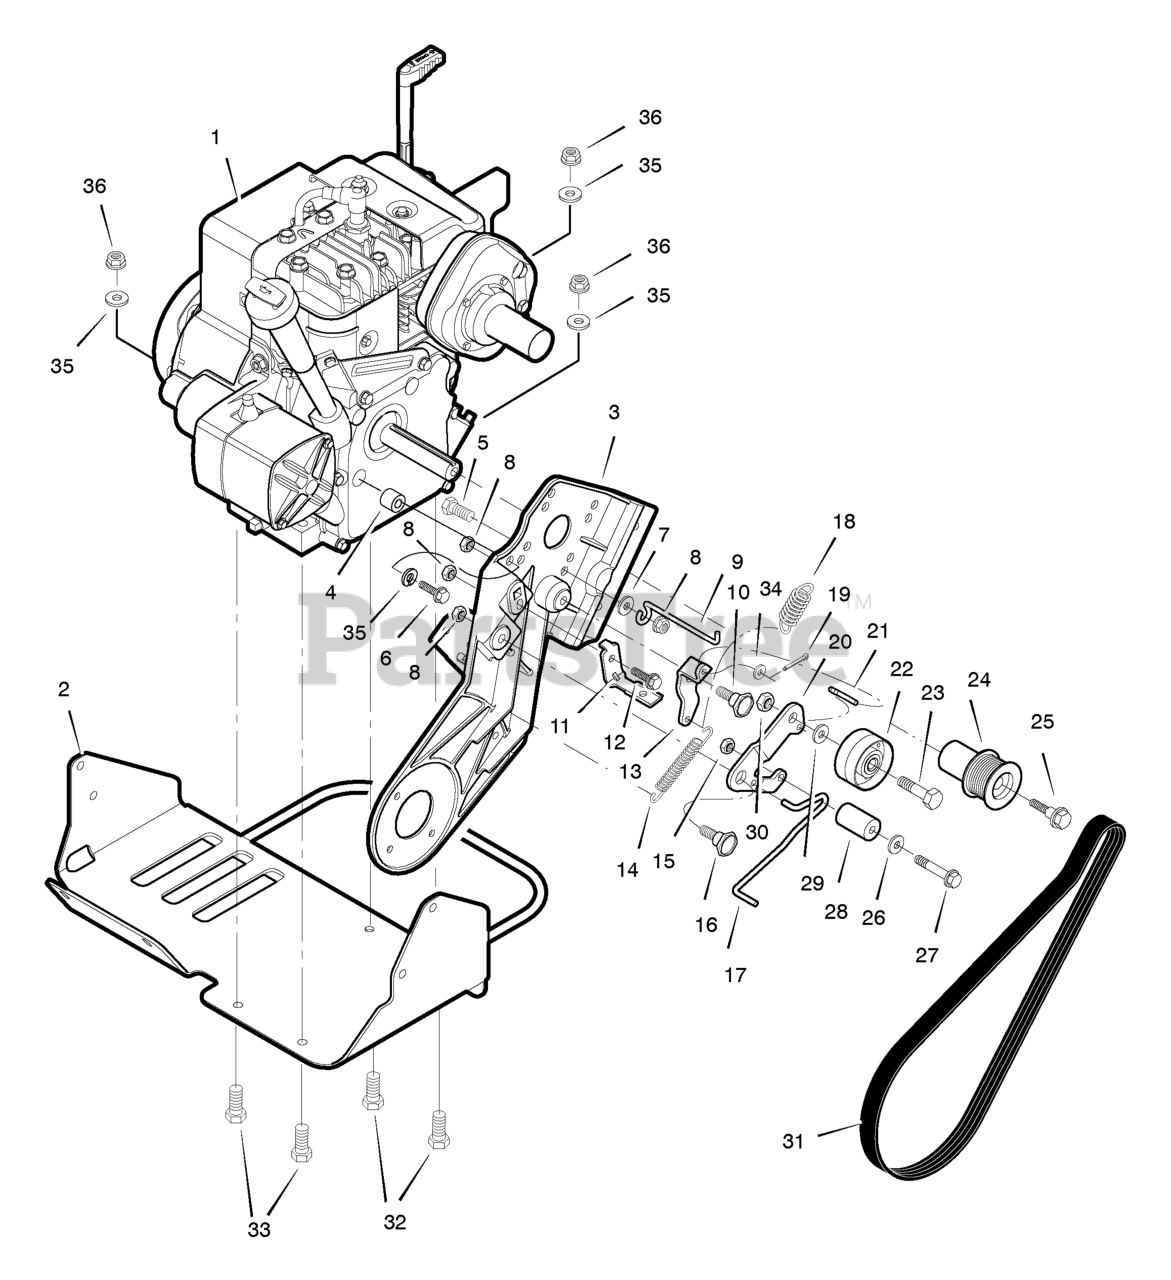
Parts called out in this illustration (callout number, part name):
1	Engine, 5HP 4CY B&S
2	Cradle Assembly, Engine
4	Antivibration Mount, Engine
5	Bolt, Hex 5/16-18 x 0.865
6	Bolt, Hex 5/16-24X1.125
7	Washer, Flat
8	Locknut, Hex Center 5/16-18
9	Guide, Belt
11	Pad, Brake
12	Screw, 1/4-20 x .63
13	Idler, Arm Pivot
15	Nut Hex 1/4-20
17	Wire, Brake
19	Pin, Cotter
20	Arm, Idler
21	Rod, Clutch Linkage
22	Pulley, Idler
23	Screw, 3/8-16 x 1.50
24	Pulley, Model 9 Engine
25	Bolt, Engine Pulley
26	Washer, Flat
27	Screw, 1/4-20 x 2.00
28	Pinch Roller
29	Washer, Flat
30	Nut, Hex
31	Belt, Drive
32	Bolt, Hex 5/16-18
33	Screw 3/8-16X1.00
34	Washer, Flat
35	Lockwasher, Split
36	Nut, 5/16-18
